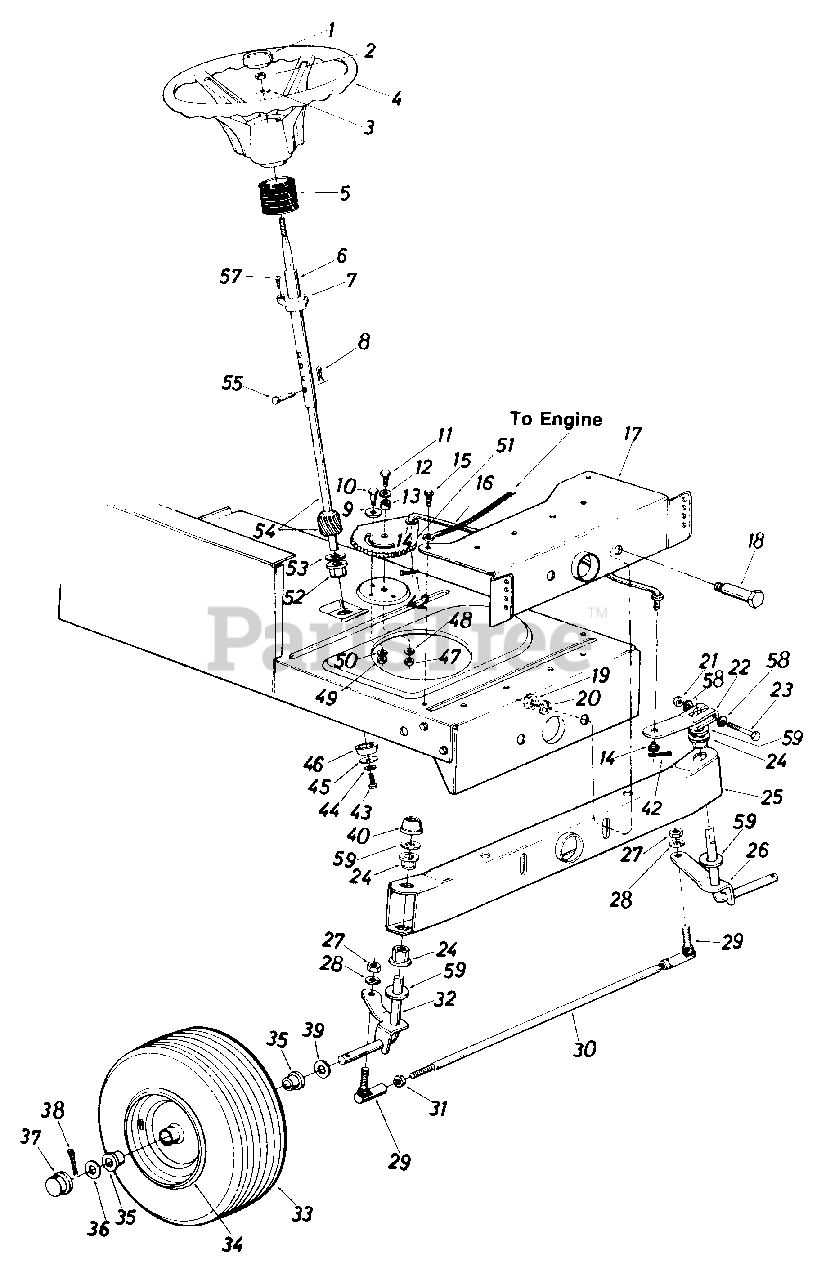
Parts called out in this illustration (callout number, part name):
1	Steering Wheel Cap
2	Hex Nut 5/16-18 Thd.
3	Belleville Wash. .345" I.D.
4	Steering Wheel 12" Dia.
5	Steering Bellow
6	Steering Column Ass'y.
7	Flange Bearing .890 I.D. x 1.36 O.D.
8	Internal Cotter Pin 1/4" Dia.
9	Fl-Wash. .438" I.D. x 1.37" O.D.
10	Shoulder Bolt .437" Dia. x .35 Lg. 5/16-18 Thd.
11	Hex Bolt 3/8-24 x 1.0" Lg. Grade 5
12	Fl-Wash. .38" I.D. x 1.0" O.D.
13	Spacer .380" I.D. x .625" O.D. x .227
14	Flat Washer .56 I.D. x 1.0 O.D.
15	Hex Wash. Hd. Self-Tap Scr.
16	Steering Drag Link
17	Front Pivot Brk't.
18	Shoulder Bolt .498" Dia. x 2.04 Lg. 3/8-16 Thd.
19	Hex Nut 3/8-16 Thd.
20	L-Wash. 3/8 I.D.
21	Hex Cent. L-Nut 5/16-24 Thd.
22	Steering Arm Front Axle
23	Hex Bolt 5/16-24 x 2.00" Lg. Grade 5
24	Hex Flg. Brg. .634 I.D.
26	Front Axle Ass'y. L.H.
27	Hex Nut 3/8-24 Thd.
28	L-Wash. 3/8 I.D.
29	Ball Joint 3/8-24 Thd.
30	Tie Rod
31	Hex Jam Nut 3/8-24 Thd.
32	Front Axle Ass'y. R.H .
33	Wheel Ass'y. Comp.
34	Front Wheel Rim Only
35	Bearing
36	Fl-Wash. .635 I.D. x 1.59" O.D.
37	Front Wheel Hub Cap
38	Cotter Pin 118" Dia. x 1.25" Lg.*
39	Fl-Wash. .635" I.D. x 1.20" O.D.
40	Push Cap 5/8" Dia. Rod
42	Cotter Pin 118" Dia. x 1.0" Lg.
43	Hex L-Bolt 5/16-18 x .62" Lg.*
44	L-Wash. 5/16" I.D.
45	Fl-Wash. .344" I.D. x 1.25" O.D.
46	Spacer (Plastic)
47	Hex Nut 3/8-24 Thd.
48	L-Wash. 3/8 I.D.
49	Hex Nut 5/16-18 Thd.
50	L-Wash. 5/16" I.D.
51	Steering Gear Segment
52	Hex Flg. Brg. .634 I.D.
53	Fl-Wash. (Hardened)
54	Steering Shaft Lower
55	Clevis Pin 1/4" Dia. x 1.00" Lg.
57	Oval Hd. Cr. Sunk Scr. #10 x 5/8" Lg.
58	Bell-Wash.
59	Fl-Wash. (Hardened)
